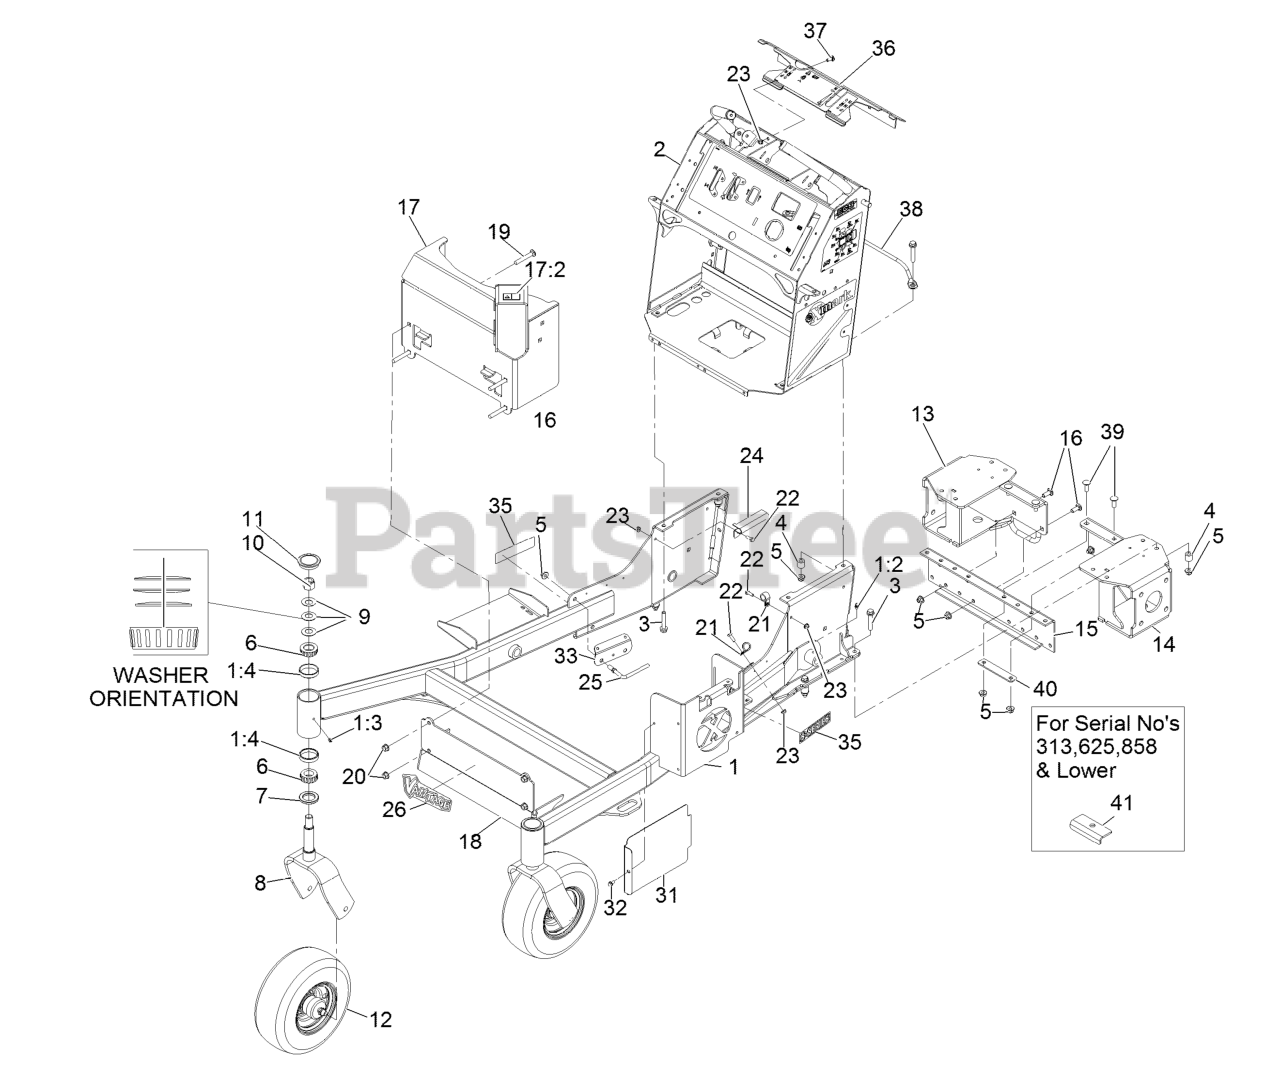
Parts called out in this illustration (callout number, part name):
1	FRONT FRAME ASM
1:2	FITTING-GREASE
1:4	CUP-BEARING
2	TOWER ASSEMBLY
3	SCREW-HHF
5	NUT-HF, NI
6	Cone-Bearing Tapered Roller
7	SEAL-GREASE
8	FORK-CASTER
9	WASHER-BELLVILLE
10	NUT-LOCK, NI
11	CAP-GREASE
12	WHEEL/TIRE AND BEARING AS
13	RH MOTOR MOUNT ASM
14	LH MOTOR MOUNT ASM
15	MOUNT-MOTOR, CENTER
16	SCREW-CARR
17:2	DECAL-WARNING
18	PANEL-GUARD
19	SCREW-CARR
21	CLAMP-CABLE
22	SCREW-HH
24	BRACKET-HOSE, FUEL
25	GUIDE-HOSE, SUPPORT
26	DECAL-VANTAGE LOGO
31	SHIELD-HEAT, TALL
32	SCREW-HWH
33	GUARD-HOSE
35	DECAL-X-SERIES
36	CONTROL PANEL W/DECALS
37	BOLT-CARR
38	ROD, GUARD
39	Bolt-Carriage 3/8-16 X 1 1/4
40	SPACER, UP STOP
41	Spacer-Up Stop
